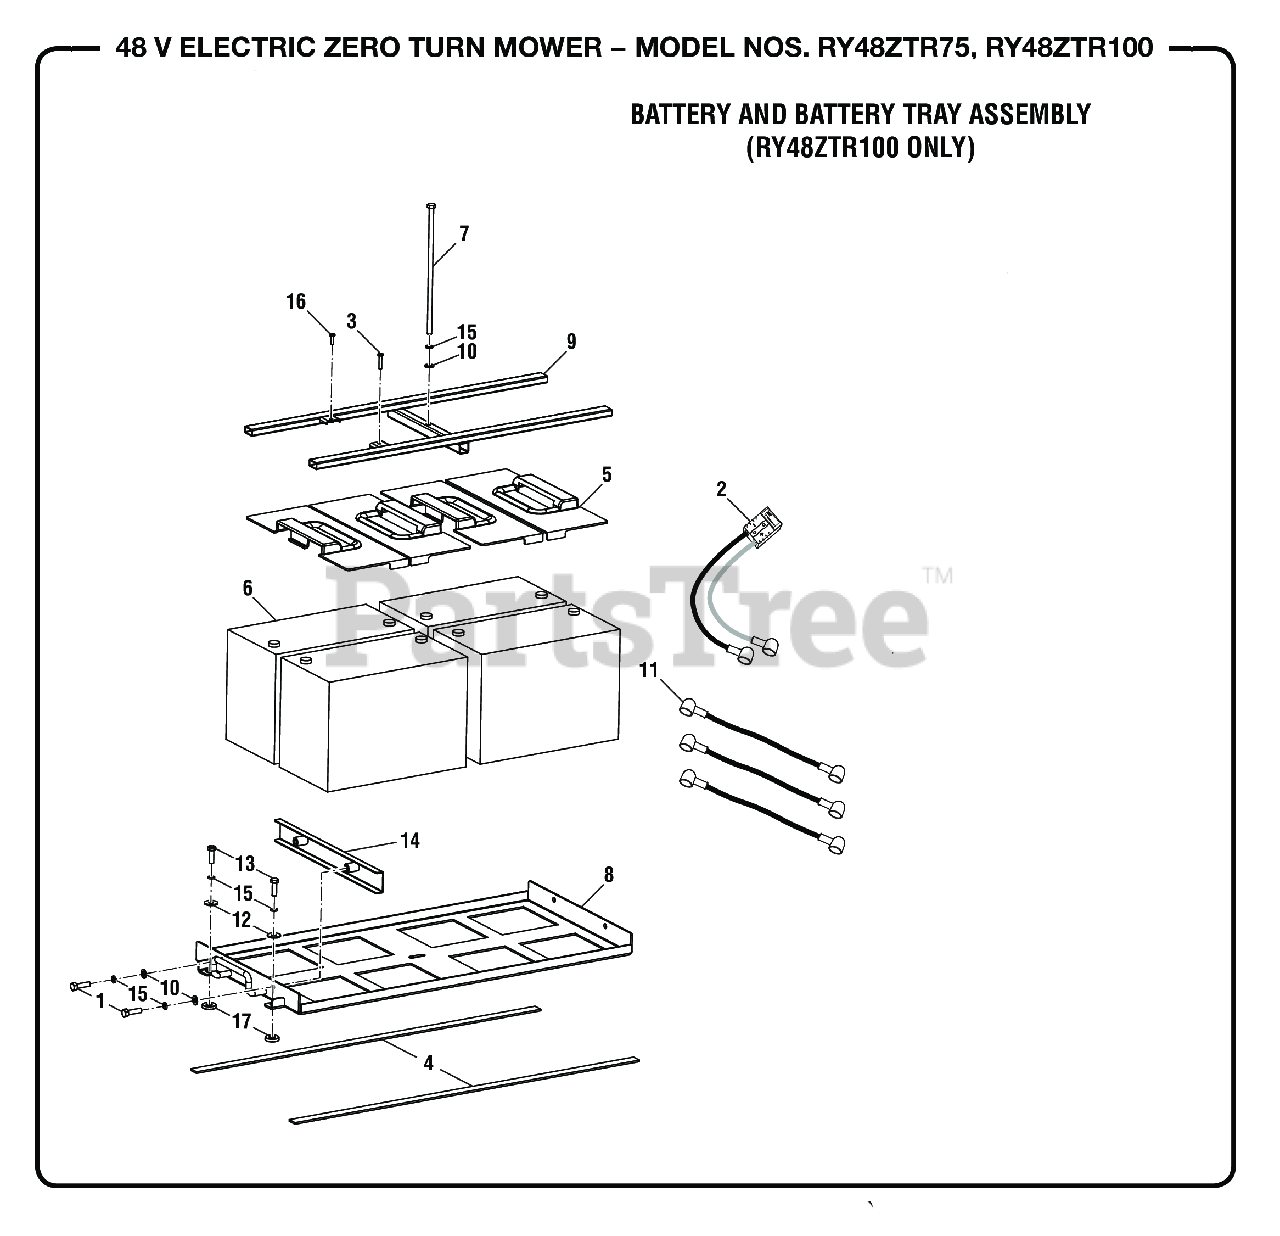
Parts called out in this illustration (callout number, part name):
1	Bolt (M8 x 25 mm)
2	Battery Cable 2, ZTR
3	Screw (M5 x 25 mm)
4	Battery Tray Slider
5	Battery Shield, ZTR
6	Battery (LPC12-75, RY48110, RY48112)
7	Hex Bolt (M8 x 240 mm)
8	Battery Tray
9	Battery Tie Down
10	Washer (OD16 x ID8.4 x 1.6t)
11	Battery Cable w/Covers (Red and Black, 120 mm)
12	Washer (OD 24 x ID8.4 x 2t)
13	Bolt (M8 x 25 mm, Hex Hd.)
14	Battery Holder Bracket
15	Lock Washer (OD9.8 x ID8.5 x 5t)
16	SCREW,PPHMS, M5 X 0.8 X 16 - STEEL,
17	Metal Bushing
